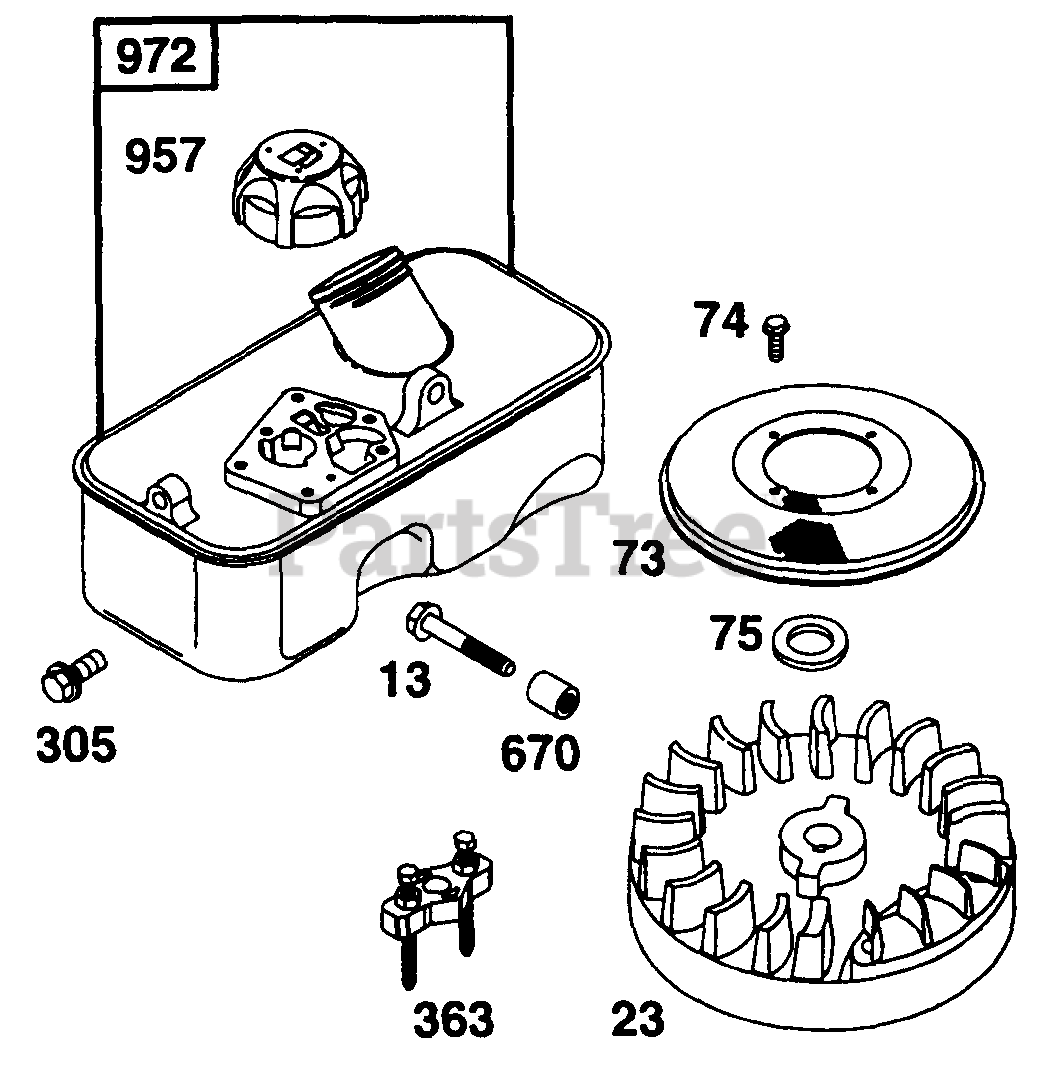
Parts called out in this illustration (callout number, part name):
13	Screw-Hex Head
73	Screen-Rotating
74	Screw-Hex Head
75	Washer-Flywheel
305	Screw-Hex Head
363	Puller-Flywheel
670	Spacer-Tank
957	Cap-Fuel Tank
